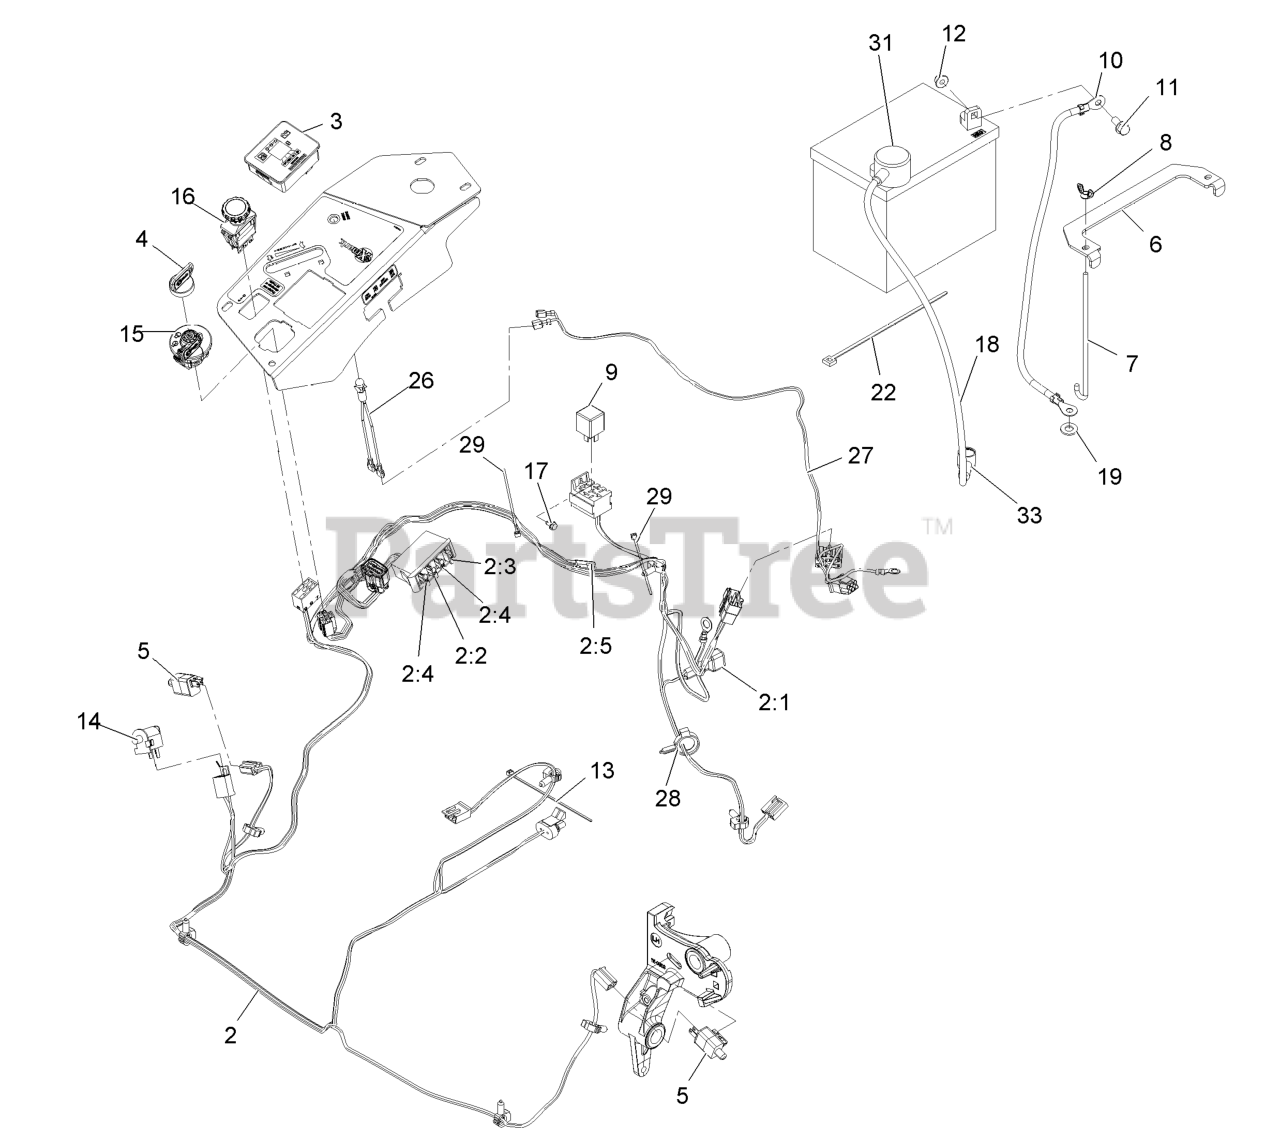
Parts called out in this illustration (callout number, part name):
2:2	FUSE-BLADE, 10 AMP
2:3	FUSE-BLADE, 15 AMP
2:4	FUSE-BLADE, 25 AMP
2:5	CAP-PLUG
3	FUEL/HOUR METER ASM
4	KEYS-IGNITION (SPARE PAIR
4	KEY-IGNITION
6	STRAP-TIE DOWN, BATTERY
7	BOLT-HOLDDOWN
8	WINGNUT
10	CABLE-BATTERY, NEGATIVE
11	SCREW-HHF
12	NUT-HF, NI
13	TIE-CABLE
14	SWITCH-BAIL
16	SWITCH-PTO, 10 AMP
17	SCREW-HWH
18	CABLE-BATTERY, POSITIVE
19	WASHER-FLAT
22	TIE-PLASTIC
26	INDICATOR-LED, RED
27	HARNESS-LIGHT, INDICATOR
28	CLAMP-HOSE
29	TIE-CABLE
31	INSULATOR-BATTERY
33	INSULATOR-SOLENOID
